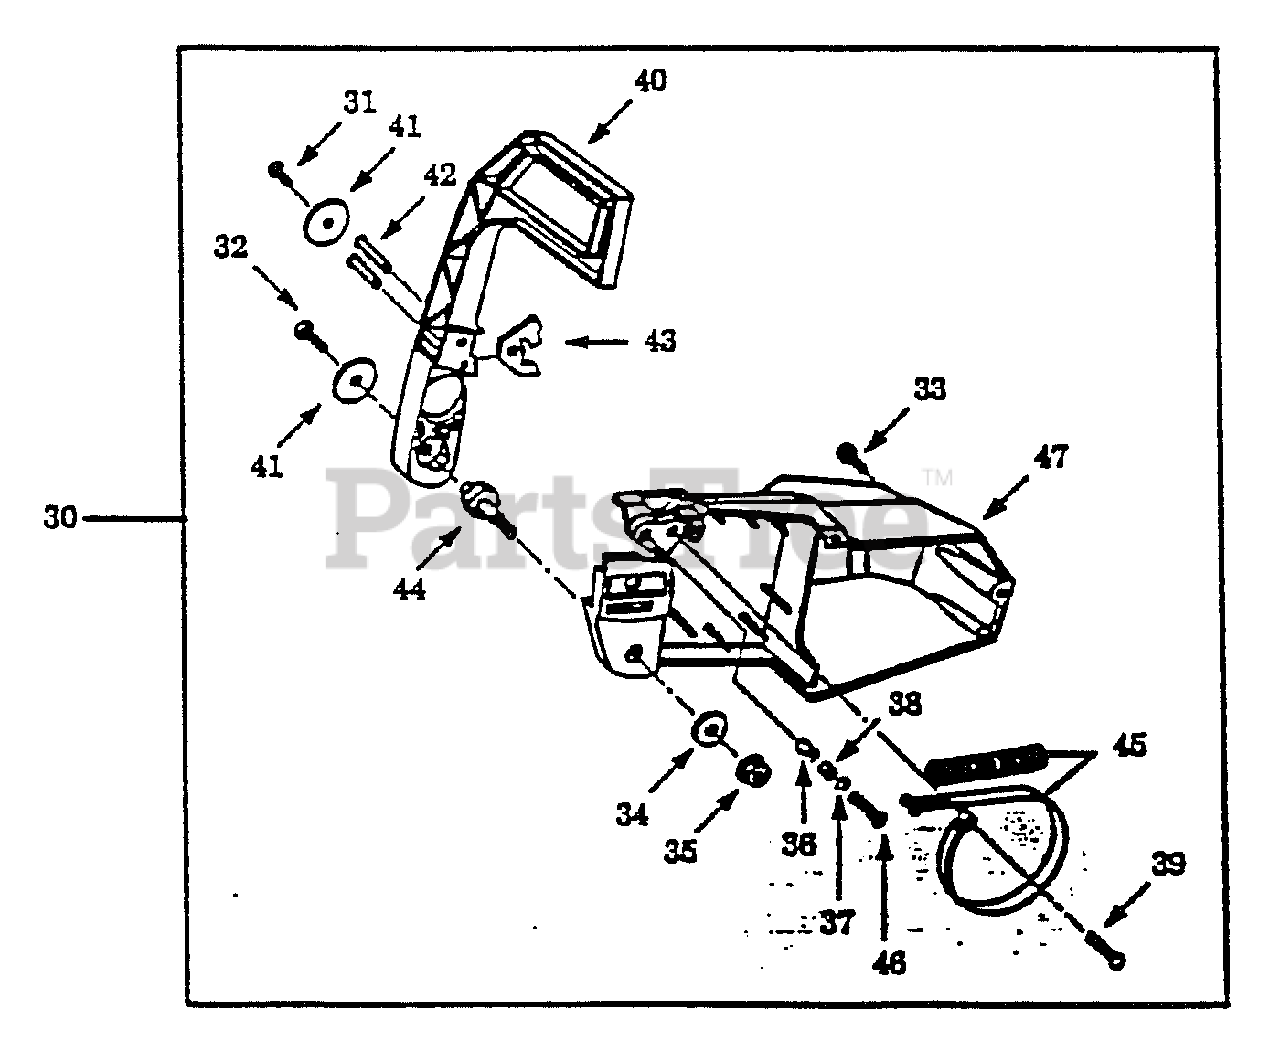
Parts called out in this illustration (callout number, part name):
30	Chain Brake Ass'y
33	Screw
35	Bar Mounting Nut
36	Latch Roller
39	Anchor Pin
40	Lever
42	Handguard Pin
44	Handguard Pivot
45	Brake Band
47	Clutch Cover
